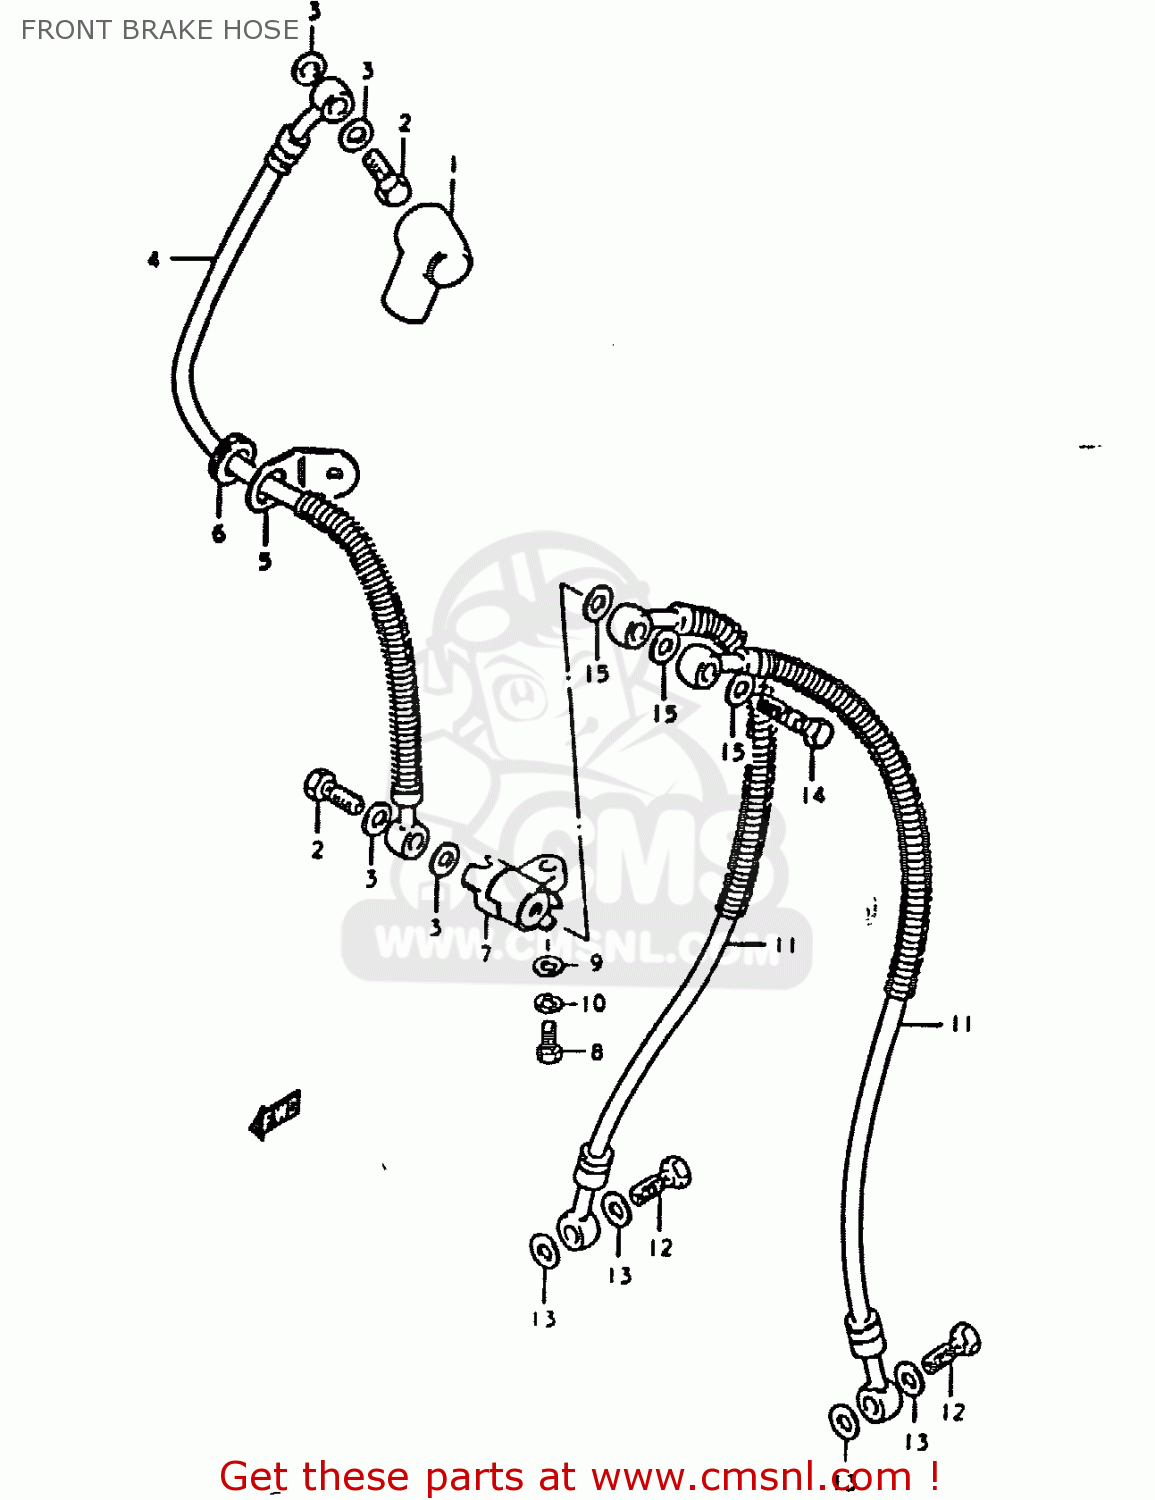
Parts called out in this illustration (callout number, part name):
1	BOOT,MASTER CYLINDER
2	BOLT UNION
3	WASHER
4	HOSE,FRONT BRAKE
5	GUIDE,BRAKE HOSE
6	GROMMET
7	JOINT,BRAKE HOSE
9	WASHER
10	LOCK WASHER
11	HOSE,FRONT BRAKE
12	BOLT UNION
13	WASHER
14	BOLT UNION
15	WASHER
